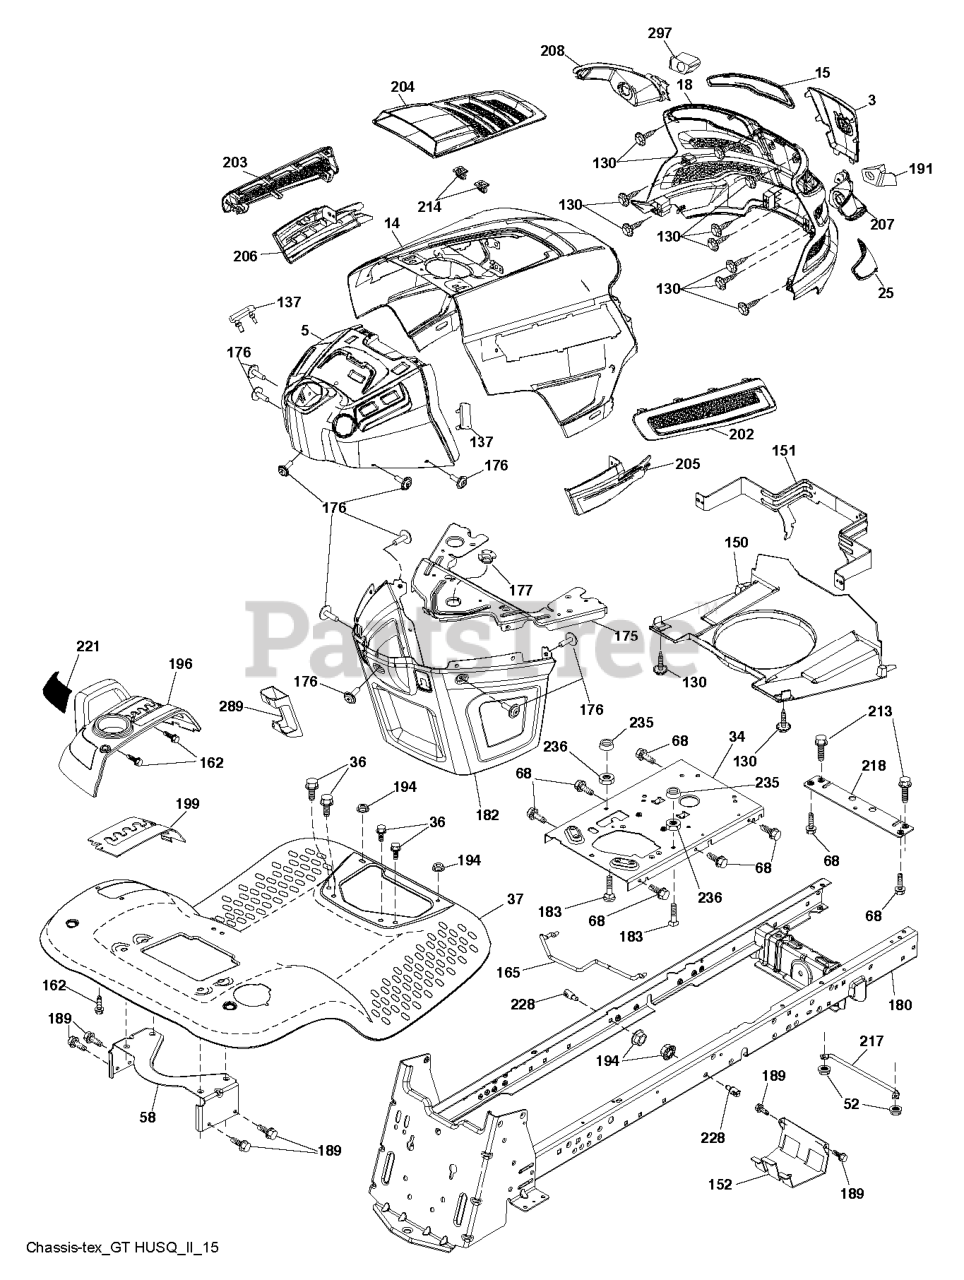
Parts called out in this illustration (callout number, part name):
3	APPLIQUE.SUBASM.GT.HUSQ.II
5	DASH.UPP.GT2.SM.PTO.MCHOKE
14	HOOD.ASM.HUSQVARNA.GT.TEX.ORAN
15	LENS.HEADLIGHT.LH.GTII.2011
18	GRILLE.SUBASM.GT.HUSQ.II
25	LENS.HEADLIGHT.RH.GTII.2011
34	PLATE.ENGINE.WELDED.CHASSIS
36	SCREW 5/16"
37	FENDER.PNT.TX.GT.CH/FW.ORANGE
52	LOCKNUT
58	BRKT.SUPPORT.FNDR/TANK
68	Screw 5/16-18 x 1/2 Hex, Self Tapping 5/16-18 x 1/2
130	SCREW.#10 X 0.750.BOS
137	BUMPER DASH
150	AIR.DUCT.GTV.BLACK
151	BRACKET.PIVOT.HOOD.GT.HUSQ.II
152	SHIELD.BROWNING.W/TEX
162	SCREW.HI-LO.CONSOLE
165	SUPPORT.TANK.REAR.W/TEX
175	PLATE.CROSSMEMBER.HUSQ
176	SCREW.#10-24X5/8.RN.QU
177	BUSHING, STEERING
180	CHASSIS.GT.SLOPED.DRAWBAR.
182	DASH.LOWER.COMMON.12V.ADAPTOR
183	BOLT.5/16-18X1-1/4 FULL.THREAD
189	SCREW
191	INSERT.REFLECTIVE.RH.HUSQ.GTII
194	NUT LOCK HEX FLANGE 5/16-18
196	RP CONSOLE.ASM.DECKLFT.W/
199	PLATE.DECK.LIFT.HUSQVARNA.GT
202	VENT.SIDE.RH.GT.HUSQ.II.
203	VENT.SIDE.LH.GT.HUSQ.II.498
204	VENT.TOP.HUSQ.GT2
205	SIDE.TRIM.RH.GT.HUSQ.II
206	SIDE.TRIM.LH.GT.HUSQ.II.GRAY
207	BEZEL LIGHT.RH.GT.II.MYLAR
208	BEZEL LIGHT.LH.GT.II.MYLAR
213	BOLT
214	CLIP.RETAINER.TINNER.
217	ROD.PIVOT.HOOD
218	X-PIECE.HOOD.STOP.NON/
221	REFLECTOR.LH.TEX GT HU
228	STUD.FASTNER.W/ANTI-ROTATE
235	SPACER FENDER
236	NUT.CENTERLOCK.5/16-
289	PLUG.N/CRUISE.COMMON.YT/GT.BLK
297	INSERT.REFLECTIVE.LH.HUSQ.GTII
